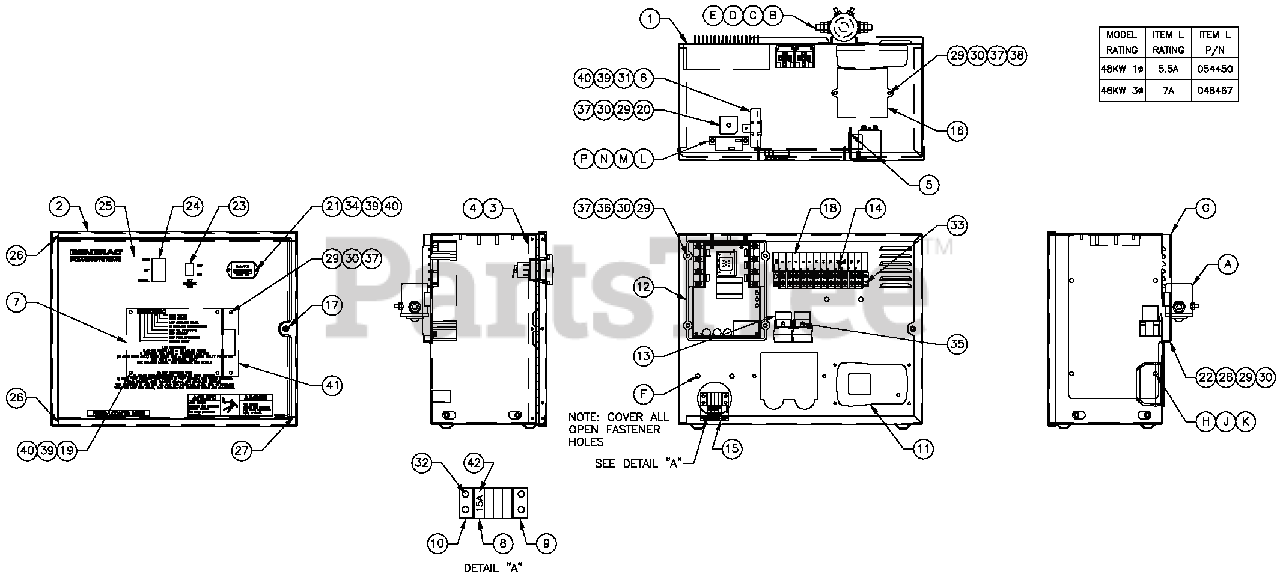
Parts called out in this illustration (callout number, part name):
1	ENCLHSBCONTROL PANEL
2	COVER CONTROL PANEL R-200B
3	HINGE CONTINUOUS H-PANEL
4	RIVET POP .125 X .275 SS
5	SCREWPPPH HI-LO#4-24X3/8
6	WASHER FLAT M3
7	ASSY PCB R200B CNTRL 1800 RPM
8	HOLDERFUSEWICKMANN 178.6150
9	ADPTR RH SIDE WICKMANN 178.6191
10	ADPTR LH SIDE WICKMANN 178.6192
11	BATC 13.4VDC 2.5A W/4POS PLUG
12	ASSY PCB HI-PWR VOLTAGE RGLTR
13	RELAY 12VDCC FORMW/DIODE
14	BLOCK TERM 20A 12X 6X1100V
15	DECAL CPL CNTPNL FUSES
16	ASSY PCB BOSCH GOV DRIVER
17	M5X0.8 CAPTIVE PANEL KNLD HD
18	DECAL CPL 3.9LTB1
19	SPACER 9.5H 3 2 ID
20	DIO BRIDGE 25A 600V
21	HOUR METER 10-80VDC
22	PLATE HARNESS CLAMP
23	SWITCH RKRDPST 125V SPD
24	SWITCH RKR DPDT ON-OFF-ON
25	DECAL CONTROL FLEXR-200B
26	SEAL COVER 3.18X12.7X382
27	SEAL COVER 3.18X12.7X283
28	SCREW HHPMM5-0.8X 12
29	WASHER FLAT M5
30	WASHER LOCK M5
31	RES WW15R 5% 25W QK CONN
32	SCREW PHTT M3.5-0.6X10
33	SCREW PHTT M3.5-0.6X16
34	SCREWPHM M3-0.5X 1 0 BLACK
35	SCREW PHTT M4-0.7 X 1 0 ZYC
36	SCREW PPHMM5-0.8 X 50ZNC
37	NUT HEXM5-0.8G8 YEL CHR
38	SCREW PPHM M5-0.8 X 30S S
39	WASHER LOCK M3
40	NUT HEXM3-0.5G8 YEL CHR
41	SUPPORT ANGLE PCB
42	FUSE ATO TYPE 15 AMP (BLUE)
A	RELAY SOLENOID 12VDCPNLMNT
B	SCREW HHC 1/4-20X3/4 G5
C	WASHER FLAT 1/4-M6ZINC
D	WASHER LOCK M6-1/4
E	NUT HEX 1/4-20STEEL
F	SEAL WEATHER .45"DIA
G	COVER CONTROL PANEL SIDE
H	SCREW PPHM M5-0.8 X 12ZNC
J	WASHER LOCK M5
K	WASHER FLAT M5
L	DPE BREAKER
M	WASHER FLAT M3
N	WASHER LOCK M3
P	NUT HEXM3-0.5G8 YEL CHR
